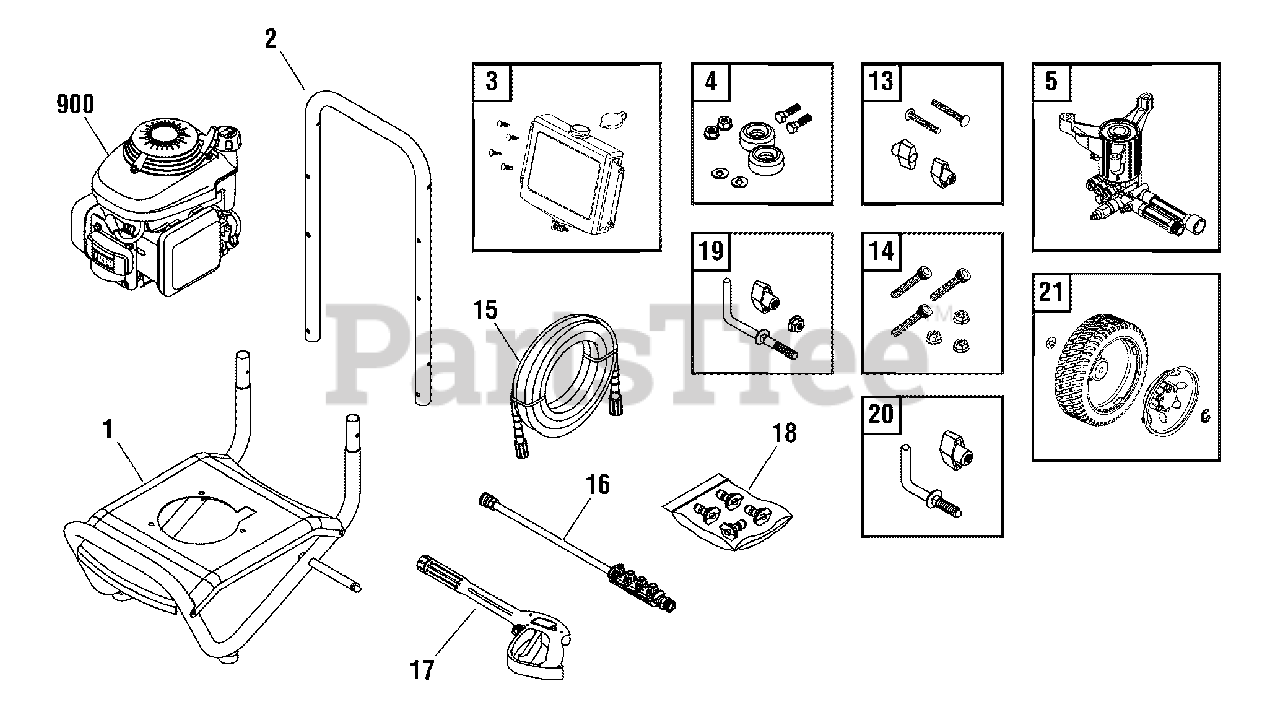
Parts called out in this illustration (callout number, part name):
4	MOUNT, Vibration
5	PUMP
13	KIT, Hardware, Handle
14	KIT, Hardware, Pump Mounting
15	HOSE
16	EXTENSION, QC
17	GUN
18	KIT, QC Nozzles
900	* ENGINE
